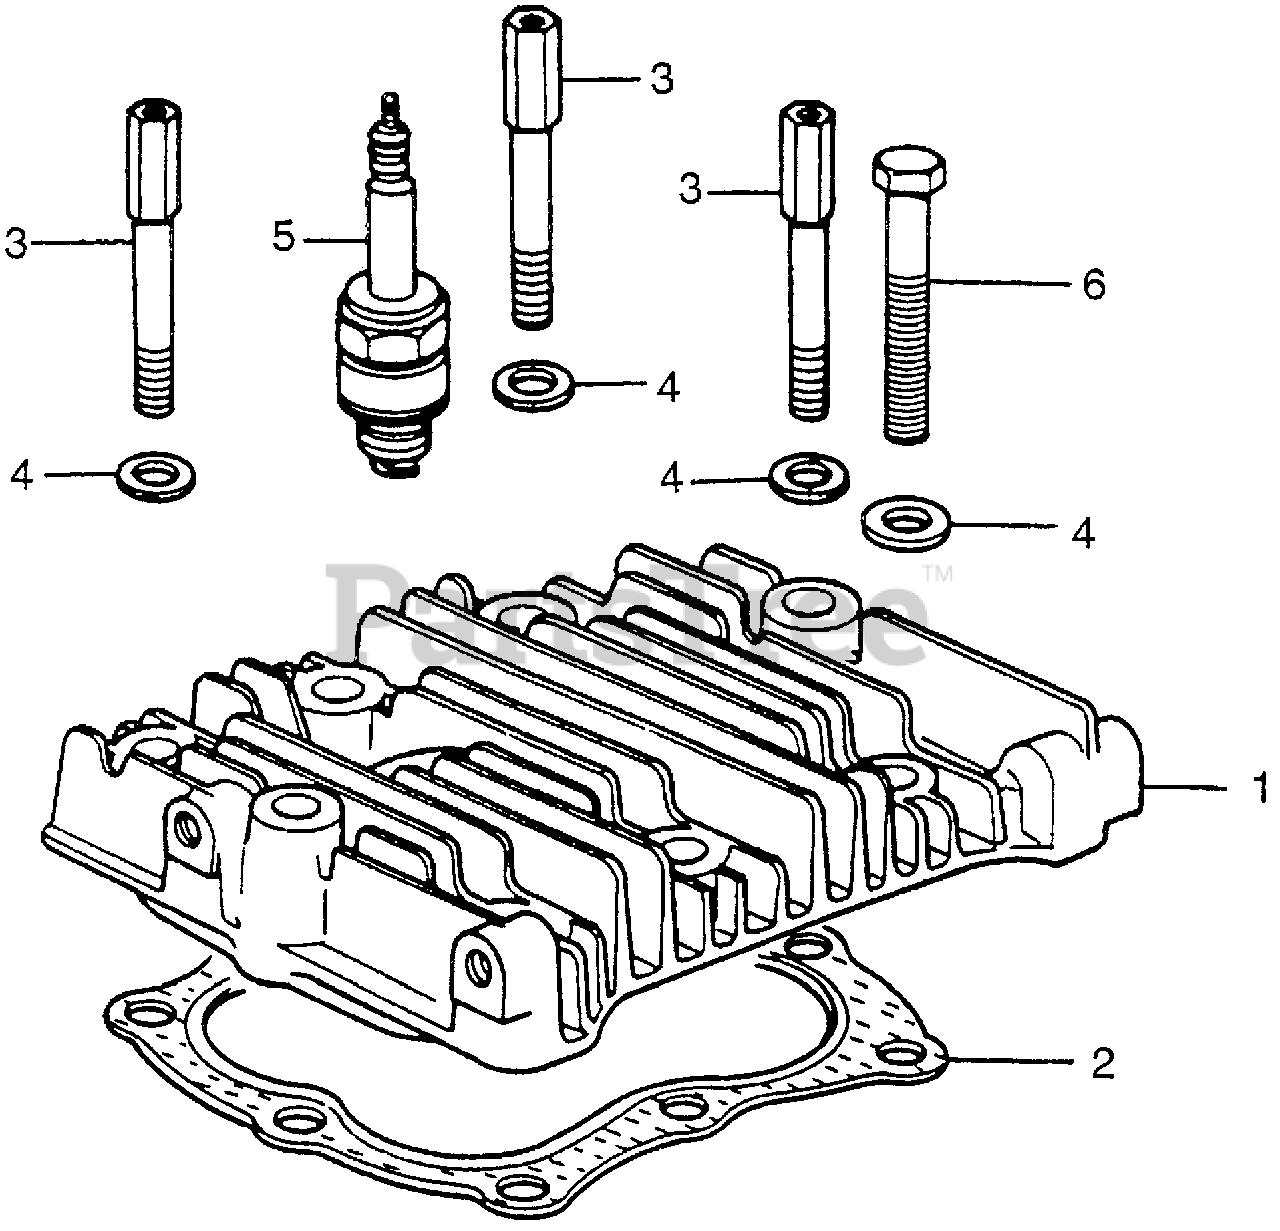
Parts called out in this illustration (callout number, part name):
1	CYLINDER HEAD
2	GASKET, CYLINDER HEAD
3	BOLT, CYLINDER HEAD CLAMP
4	WASHER, HEAD (8MM)
5	SPARK PLUG (B6HS) (NGK)
6	BOLT, HEX. (8X45)
